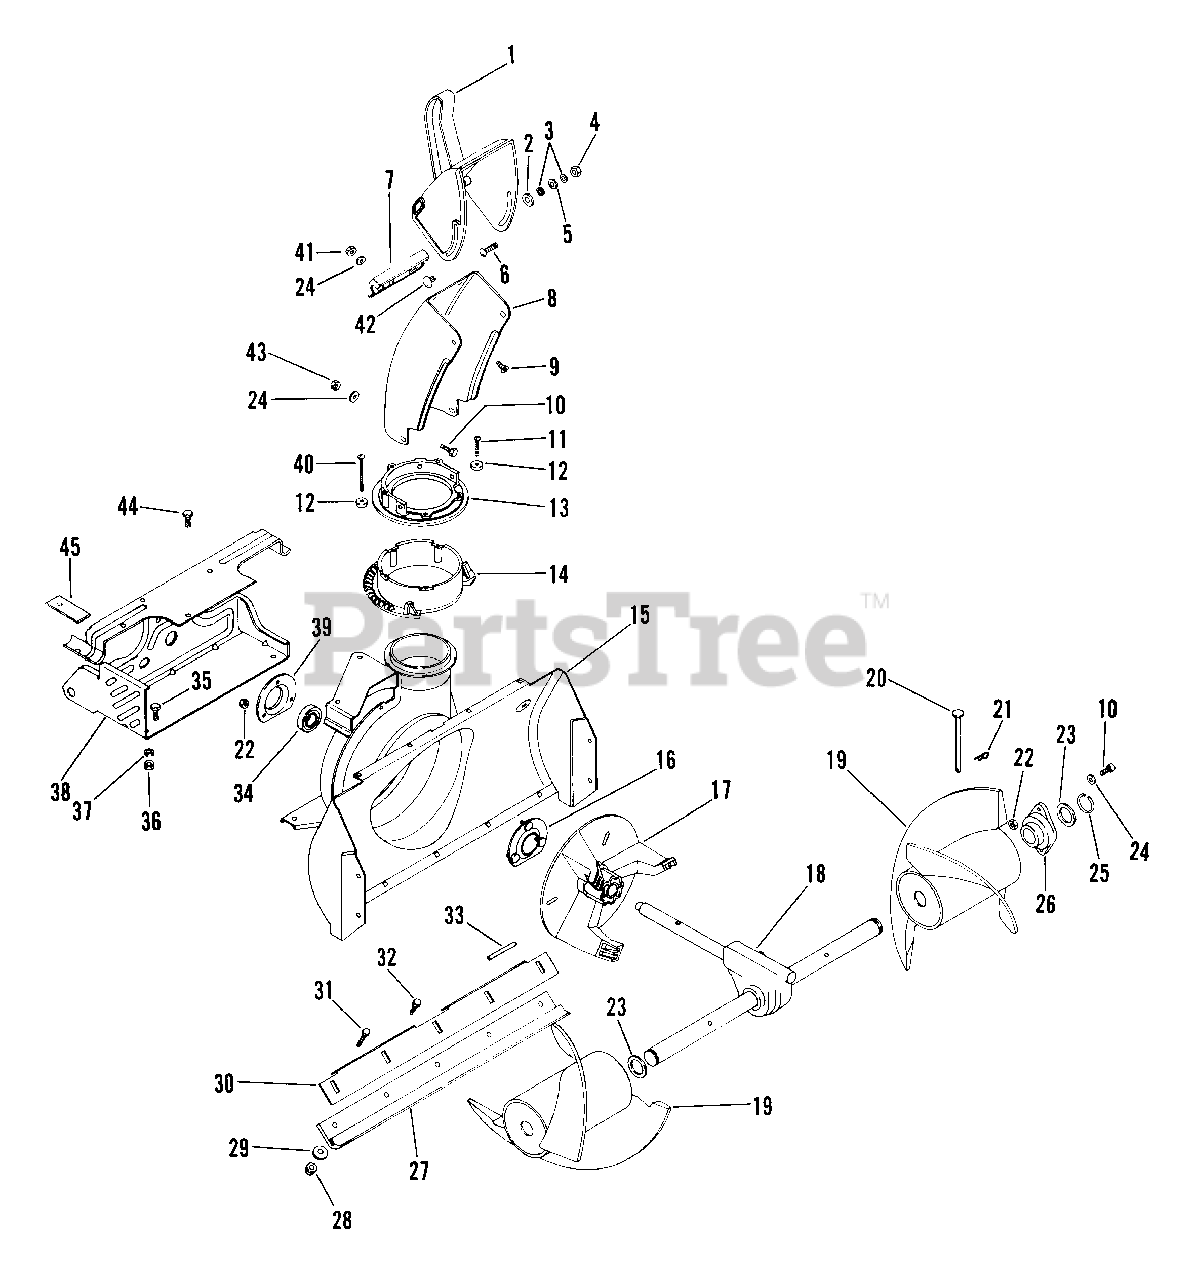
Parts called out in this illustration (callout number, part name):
1	DEFLECTOR CAP W/DECAL
2	WSHR-PLASTIC .390X.875X.062
3	WSHR-FL-STL .323X.625X.062 PL
4	NUT-LK .312-18 GR A PL
5	WAVE WASHER .390X.655X.110
6	BLT-RDHDSQNK .31-18X1.0 SHT PL
7	HINGE
8	DISCHARGE CHUTE
9	SCR-SKH .25-20X.75 FLTCNTRSK
10	SCR-SKH .25-20X.62 BTNHD GR5
11	SCR TAP 8-18X1.50 SL HWH PL B
12	WSHR-FL-NY .21X.75X.180
13	RING
13	CHUTE GEAR
15	AUGER HOUSING
16	BEARING FLANGE
17	IMPELLER-3 BLADE
18	GEAR CASE ASSEMBLY
19	AUGER ASSEMBLY LH
19	AUGER ASSEMBLY RH
20	PIN
21	PIN COTR .09X.50 PL
22	NUT-LK-CTR .250-20 PL
23	WSHR-FL-STL 1.010X1.505X.062PL
24	WSHR-FL-STL .281X.625X.065 PL
25	RG-RTNG-EXT 1.00X.042
26	BEARING SUPPORT
27	SCRAPER BLADE
28	NUT-LK-FLG .250-20 PL
29	WSHR-FL-STL .328X.875X.062 PL
30	SCRAPER SUPPORT
31	BLT-RDHDSQNK .25-20X.88 PL
32	BLT-RDHDSQNK .25-20X.75 GR5PL
33	PIN-ROLL .250X2.00
34	BRG-BALL .750X1.750X.50
35	BLT-HEX .31-18X.63 PL GR 2
36	NUT-HEX .312-18
37	WSHR-LK .312X.097 PL HVY
38	FRAME WELDMENT
39	BEARING FLANGE
40	SCR-TAP 8-18X2.00 SL HWH PL B
41	NUT-KEPS .250-20 PL BL
42	RVT-PUSH .28X.34 THRD-TRUSS-HD
43	NUT-LK-CTR .250-20 PL BL
44	SCR-TAP .312-18X.50 HWH PL TR
45	PAD-FOAM
